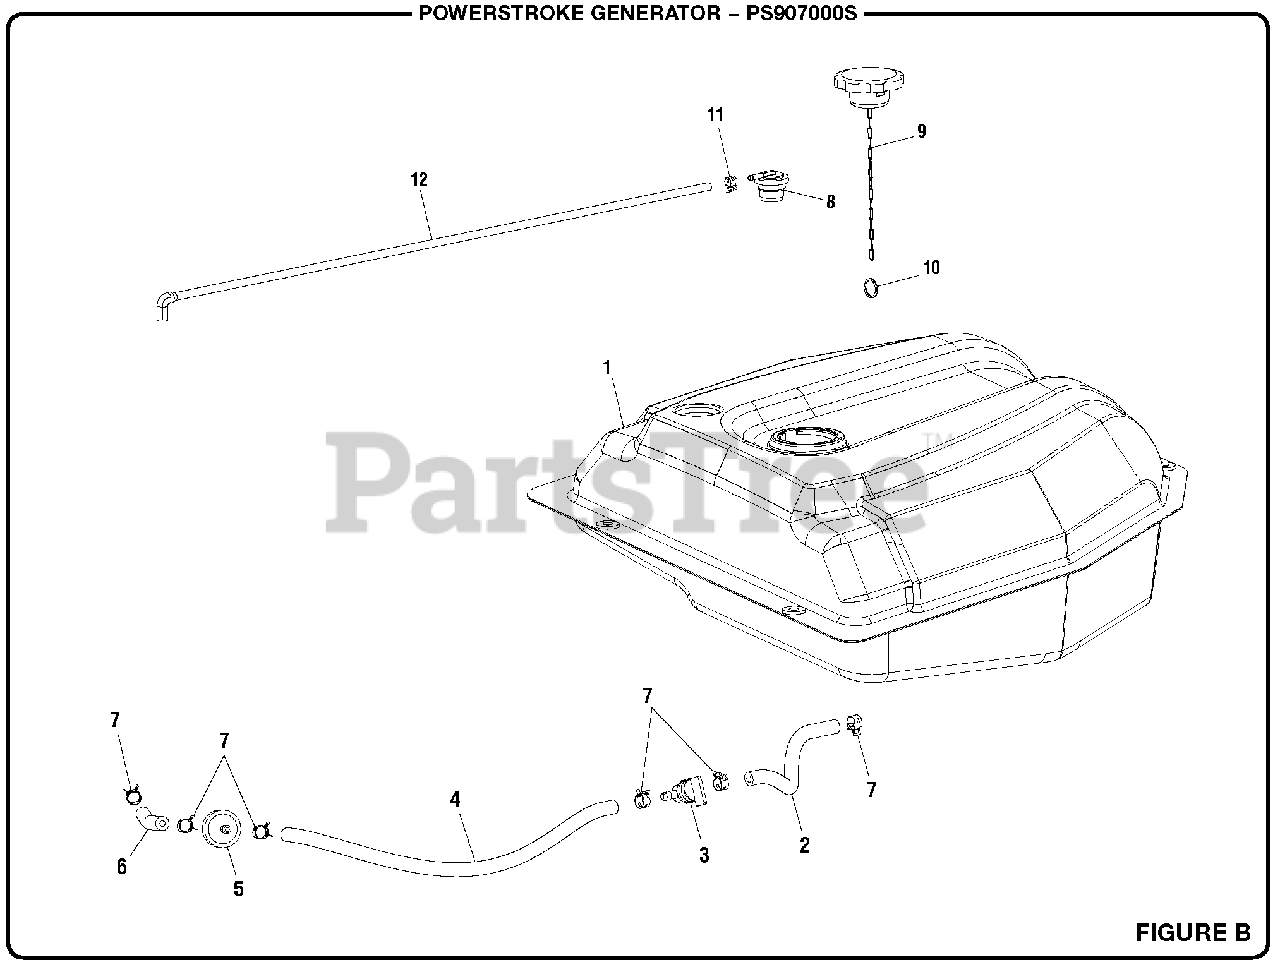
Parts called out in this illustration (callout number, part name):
1	Fuel Tank
2	Fuel Hose (55 mm)
3	Fuel Shut Off Valve
4	Fuel Hose (175 mm)
5	Fuel Filter
6	Fuel Hose (185 mm)
7	Hose Clamp (1/2 in.)
8	Vapor Vent
10	Ring Clip
11	Hose Clamp (10.3 mm)
12	Vapor Hose (590 mm)
